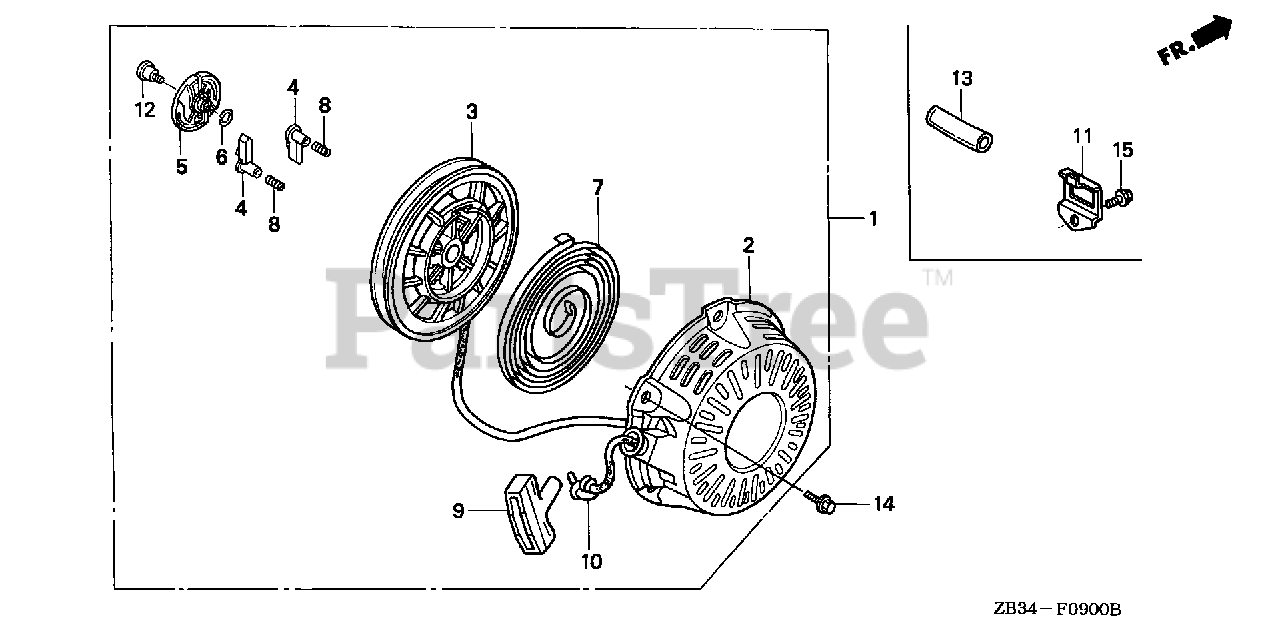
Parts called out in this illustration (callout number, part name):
1	STARTER ASSY., RECOIL *NH1* (BLACK)
2	CASE, RECOIL STARTER *NH1* (BLACK)
3	REEL, RECOIL STARTER (NATURAL)
4	RATCHET, STARTER
5	GUIDE, RATCHET
6	SPRING, FRICTION
7	SPRING, RECOIL STARTER
8	SPRING, RETURN
9	KNOB, RECOIL STARTER
10	ROPE, RECOIL STARTER
11	COVER, WIRE CLIP
12	SCREW, SETTING
13	TUBE, CORD
14	BOLT, FLANGE (6X10)
15	BOLT, FLANGE (6X10)
